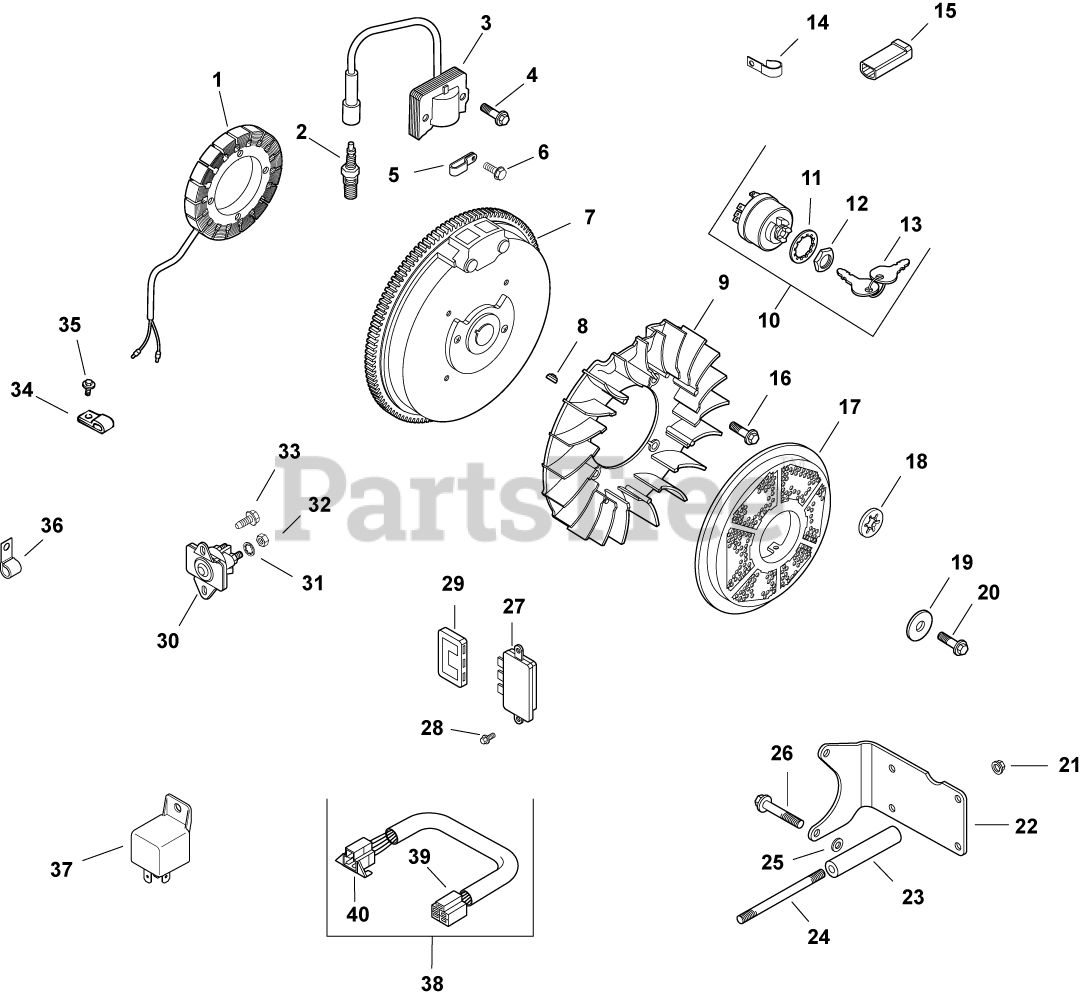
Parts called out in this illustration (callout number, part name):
1	KIT, 15 / 20 AMP STATOR
2	PLUG, SPARK (PRO SERIES)
3	MODULE, IGNITION
4	SCREW, FLG THD FRM M5X.8X20-(#25086399S)
6	SCREW, FLG THD FRM M5X.8X10
8	KEY, 3/16" X 5/8"
10	SWITCH ASSY, KEY (KM)-USE 25 099 32-S
11	WASHER, INTERNAL TOOTH
12	NUT, KEY SWITCH
13	KEY, SET -USE 48 340 01-S
14	CLIP, CABLE
15	CONNECTOR (1 CONTACT)
16	BOLT, SHOULDER
19	WASHER, FLAT 13/32"
20	SCREW, FLG M10X1.5X45 - (#25086361S)
21	NUT, FLG M8X1.25
22	BRACKET, FUEL TANK
24	STUD, M8X1.25X133-USE 25 755 54-S
25	WASHER, FLAT 11/32"
26	SCREW, FLG M8X1.25X50
27	REG/RECT-15 AMP (KM)-USE 41 403 10-S
28	SCREW, FLG M6X1.0X16
29	CONNECTOR, BODY (KM)-USE 25 155 41-S
30	SOLENOID - WATERPROOF (KM)-USE 25 435 08
31	WASHER, INT TOOTH LOCK 1/4"
32	NUT, JAM 1/4-20 GRADE 2
33	SCREW,FLG THD FRM M6X1.0X16-(#25086397S)
34	CLIP, TUBE & WIRING (KM)
35	SCREW, M5X0.8X25 - (#25086402S)
38	CONNECTOR
39	CONNECTOR ASSEMBLY
40	CONNECTOR
1251809-S	LEAD, STARTER SOLENOID - DISCONTINUED
2551829-S	LEAD, GROUND SOLENOID
